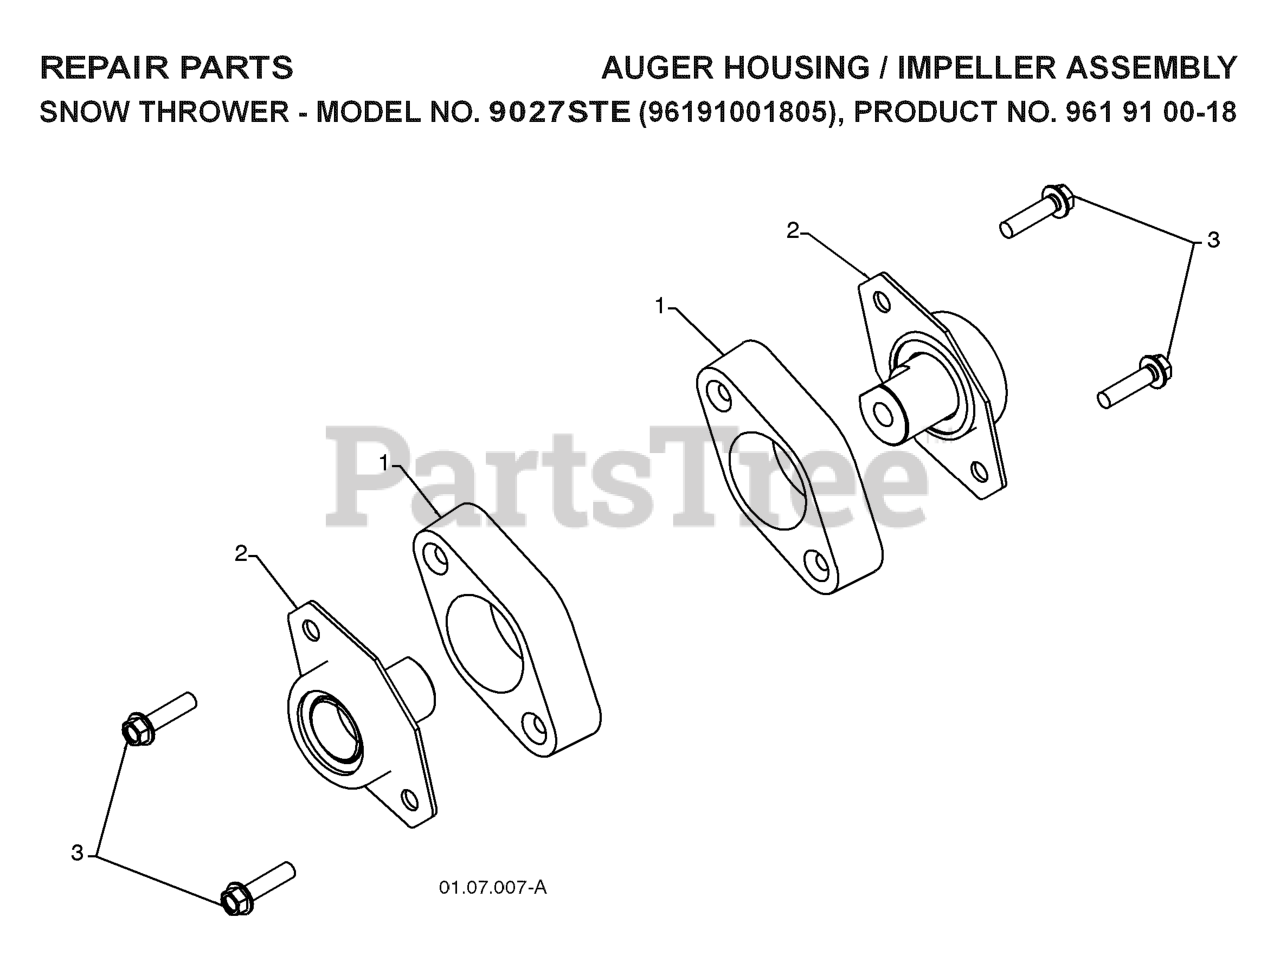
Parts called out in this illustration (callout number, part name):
1	BEARING RETAINER, PLASTIC
2	BEARING.BALL.AUGER
3	SCREW, HEX HD 5/16X1
